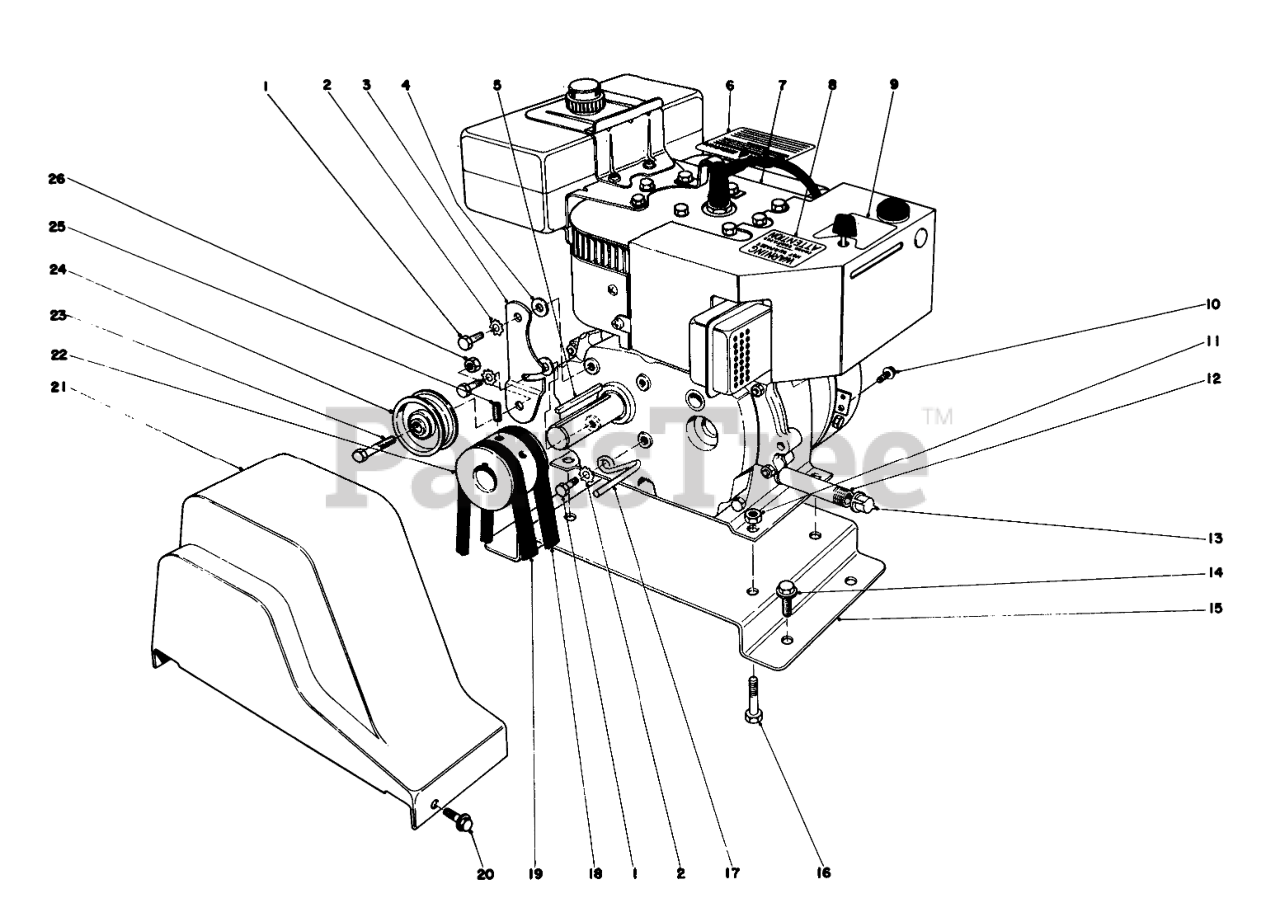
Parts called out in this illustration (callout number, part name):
1	SCREW-HH
2	WASHER-LOCK
3	ENGINE IDLER ARM
4	WASHER-PLAIN
6	CAUTION DECAL
7	Engine
8	Decal Hot Surface Warning
9	Decal-Choke & Primer
10	SCREW
11	NUT-LOCK, NI
12	NIPPLE-PIPE
13	CAP-PIPE
14	SCREW-HHFTF
15	ENG MTG PLATE R
16	SCREW-HH
17	BELT RETAINER
18	V-BELT
19	V-BELT
20	SCREW-HWH
21	BELT GUARD
22	ENGINE PULLEY
23	SCREW-HH
24	PULLEY-IDLER
25	Screw-Set
26	NUT-HEX
